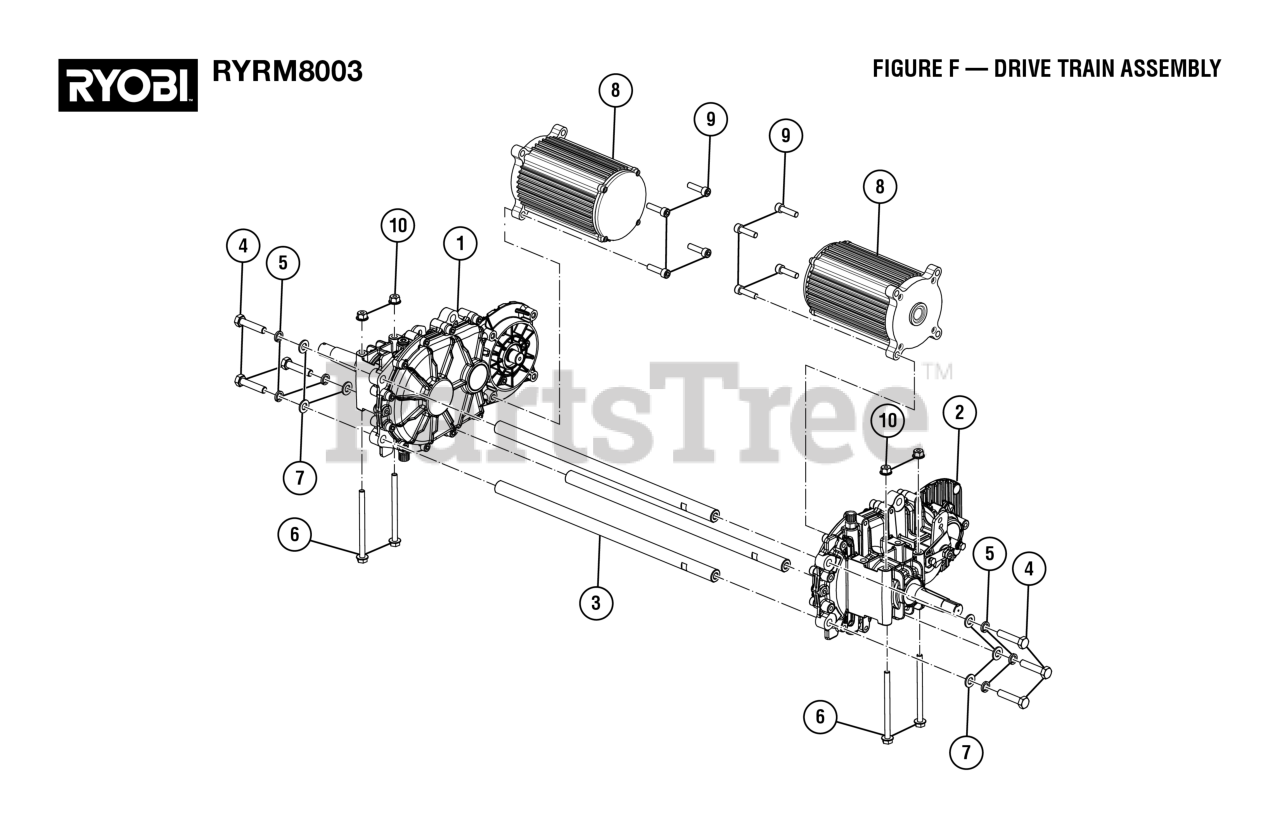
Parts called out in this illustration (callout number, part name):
1	GEARBOX, LEFT
2	GEARBOX, RIGHT
4	Bolt (M10 x 45 mm, Hex Hd.)
5	Lock Washer (M10)
6	Flange Bolt (M8 x 110 mm, Hex Hd.)
7	Washer (OD20 x ID10.5 x 2t)
8	80V Drive Motor
9	Screw (M8 x 30 mm, Soc. Hd.)
10	Flange Nut (M8) (For Drive Motor Controller V)
